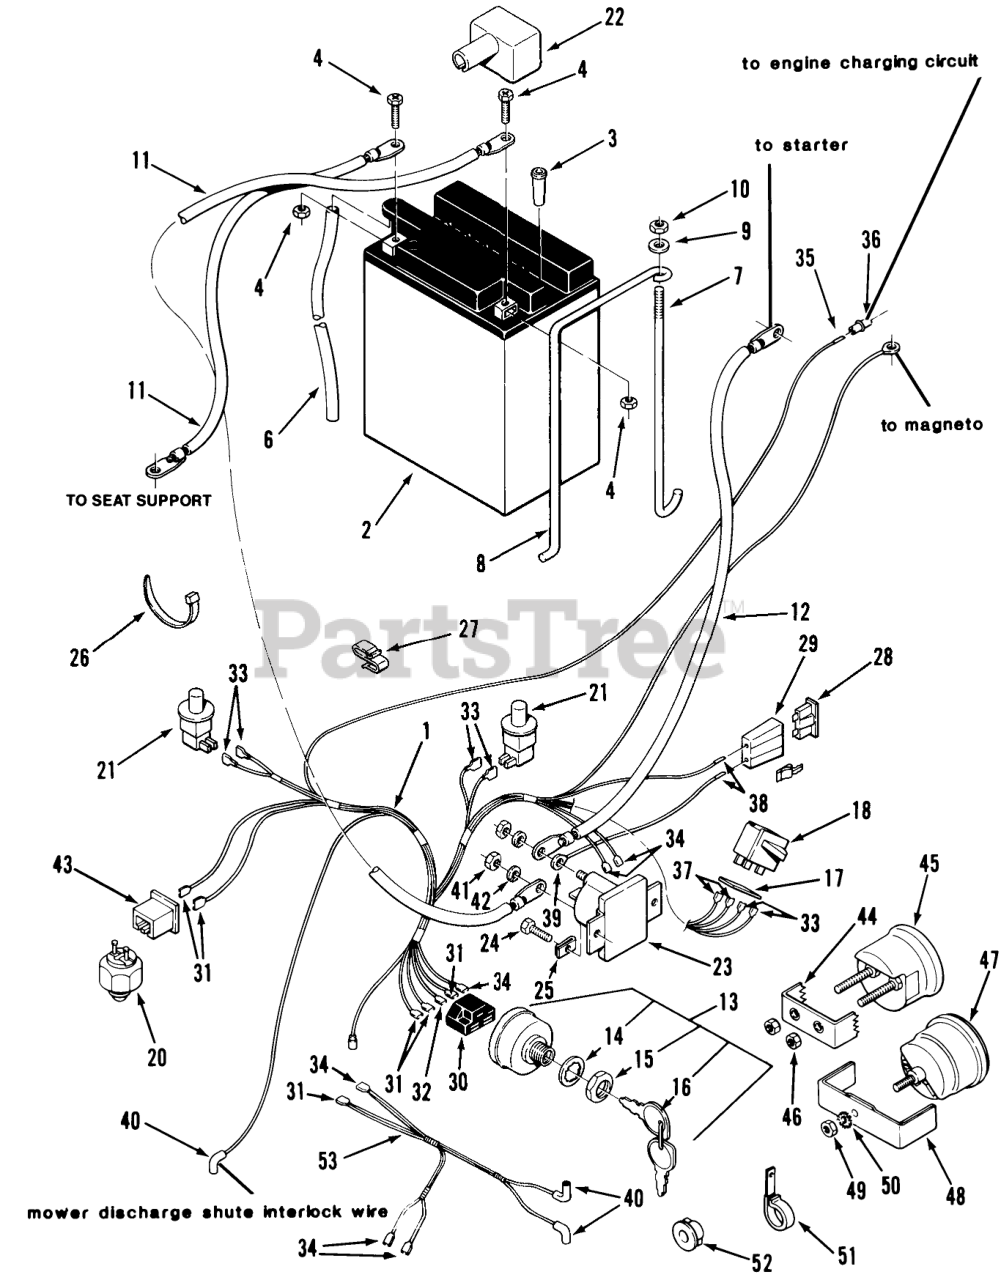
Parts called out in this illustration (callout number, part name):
1	WIRING HARNESS
2	BATTERY 120CCA
3	ADAPTER
4	ASSY BATTERY HDW
6	HOSE BATTERY DRAIN
7	HOOK-BATTERY RETAINR
8	Front Battery Hold Down Rod
10	Nut
11	WIRE -BLACK
12	WIRE ASM
13	ASSY-SWITCH IGNITION
14	LOCKWASHER
16	Key-EL
17	SHIELD-DIRT (DPDT)
18	PTO Interlock Switch
20	SWITCH-BALL
21	SWITCH (N.C.)
22	COVER-TERMINAL
23	Solenoid
24	Screw
25	Speed Nut
26	PLASTIC TIE
27	CLIP-CABLE
28	FUSE-BLADE, 15 AMP
29	AUTO-FUSEBLOCK TERM
30	CONNECTOR-5 WAY-SERV
31	Terminal
32	TERMINAL-TAB RCPT
33	Terminal
34	Connector
35	Terminal
36	SOCKET HOUSING
37	Wire Terminal (Part of 1)
38	TERMINAL-FUSE
39	Wire Terminal (Part of 1)
40	Terminal Part of 5
41	Nut
42	Washer
43	Connector Housing M
44	CLAMP MOUNTING
45	Voltmeter (w/109650)
46	HEX NUT 10-32 E.S.
47	Hourmeter 111-5 Only (Includes Clamp & Hdrw.)
48	HOUR METER CLAMP
49	Hex Nut
50	Lockwasher
51	CLAMP
52	BUSHING-NYLON .75
53	Volt & Hourmeter Harness
